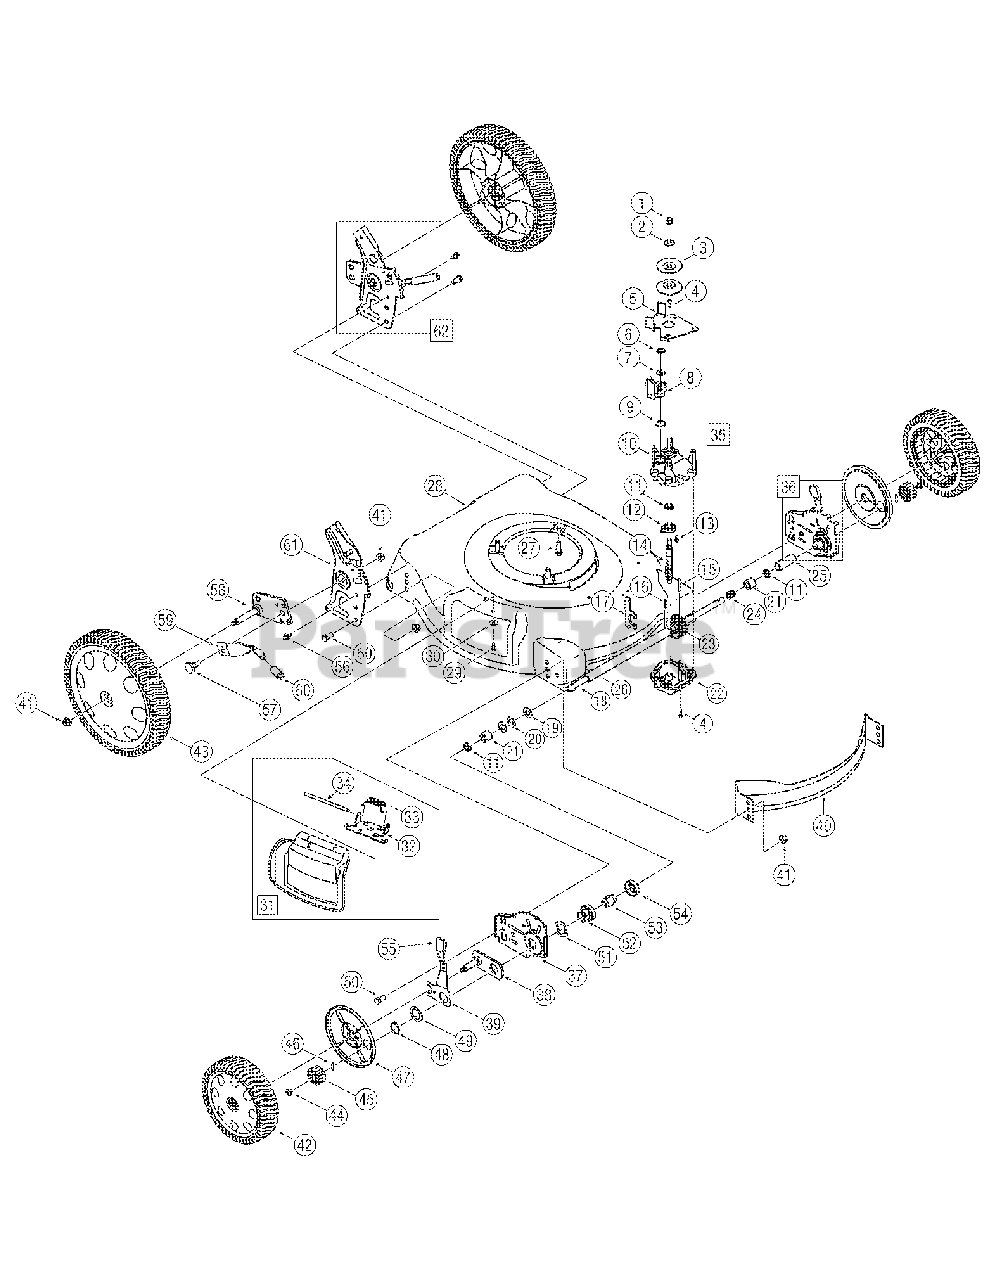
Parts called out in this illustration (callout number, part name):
1	Hex Lock Nut, 3/8-24
2	Bell Washer.325 x.930 x.45
3	Pulley, 3.82 x.313 x.68
4	Torx Screw
5	Transmission Bracket
6	Push Nut
7	Slotted Washer
8	Clutch Lever
9	O-ring
10	Upper Housing
11	Oil Seal
12	Ball Bearing
14	Pinion Shaft
15	Dowel Pin
16	Spirol Pin
17	Shifter Fork
18	Output Shaft
19	Flat Washer
20	Flat Washer
21	Plastic Bushing
22	Lower Housing
23	28 Tooth Gear
24	Compression Spring
25	Slev. Spacer 1.8" Lg.
26	Sleeve Spacer 9.10" Lg.
27	Self-Tapping Sems Screw
30	Bell Washer
31	Hinged Mulch Plug Assembly
32	Chute Deflector Adapter
33	Mulch Plug
34	Torsion Spring
34	Hinge Pin
35	Transmission Assembly
36	Height Adj. Assembly - LH
36	Height Adj. Assembly - RH
37	Front Height Adj. Plate - RH
37	Front Height Adj. Plate - LH
38	Pivot Plate Assembly
39	Front Lever - RH
39	Front Lever - LH
40	Front Baffle
41	Flange Lock Nut, 3/8-16
42	Front Wheel 8 x 2.125
43	Rear Wheel, 12 x 2.125
44	Screw 1/4-20 x .390
45	Gear 14T RH FWD RH
45	Gear 14T LH FWD LH
46	Dowel Pin
47	Wheel Dust Cap
48	Snap Ring
49	Flat Washer
50	Hex Screw, 3/8-16 x.75
51	Wave Washer
52	Bearing Support
53	Sleeve Bearing
54	Bearing Retainer
55	Adjustment Knob
56	TT Scr. w/Washer 1/4-20 x.625
57	Shoulder Scr.500 Dia. x.434
58	Pivot Arm Assembly - RH
58	Pivot Arm Assembly - LH
59	Rear Spring Lever
60	Foam Grip
61	Handle Bracket - RH
61	Handle Bracket - LH
62	Handle Bracket Assembly - LH
62	Handle Bracket Assembly - RH
